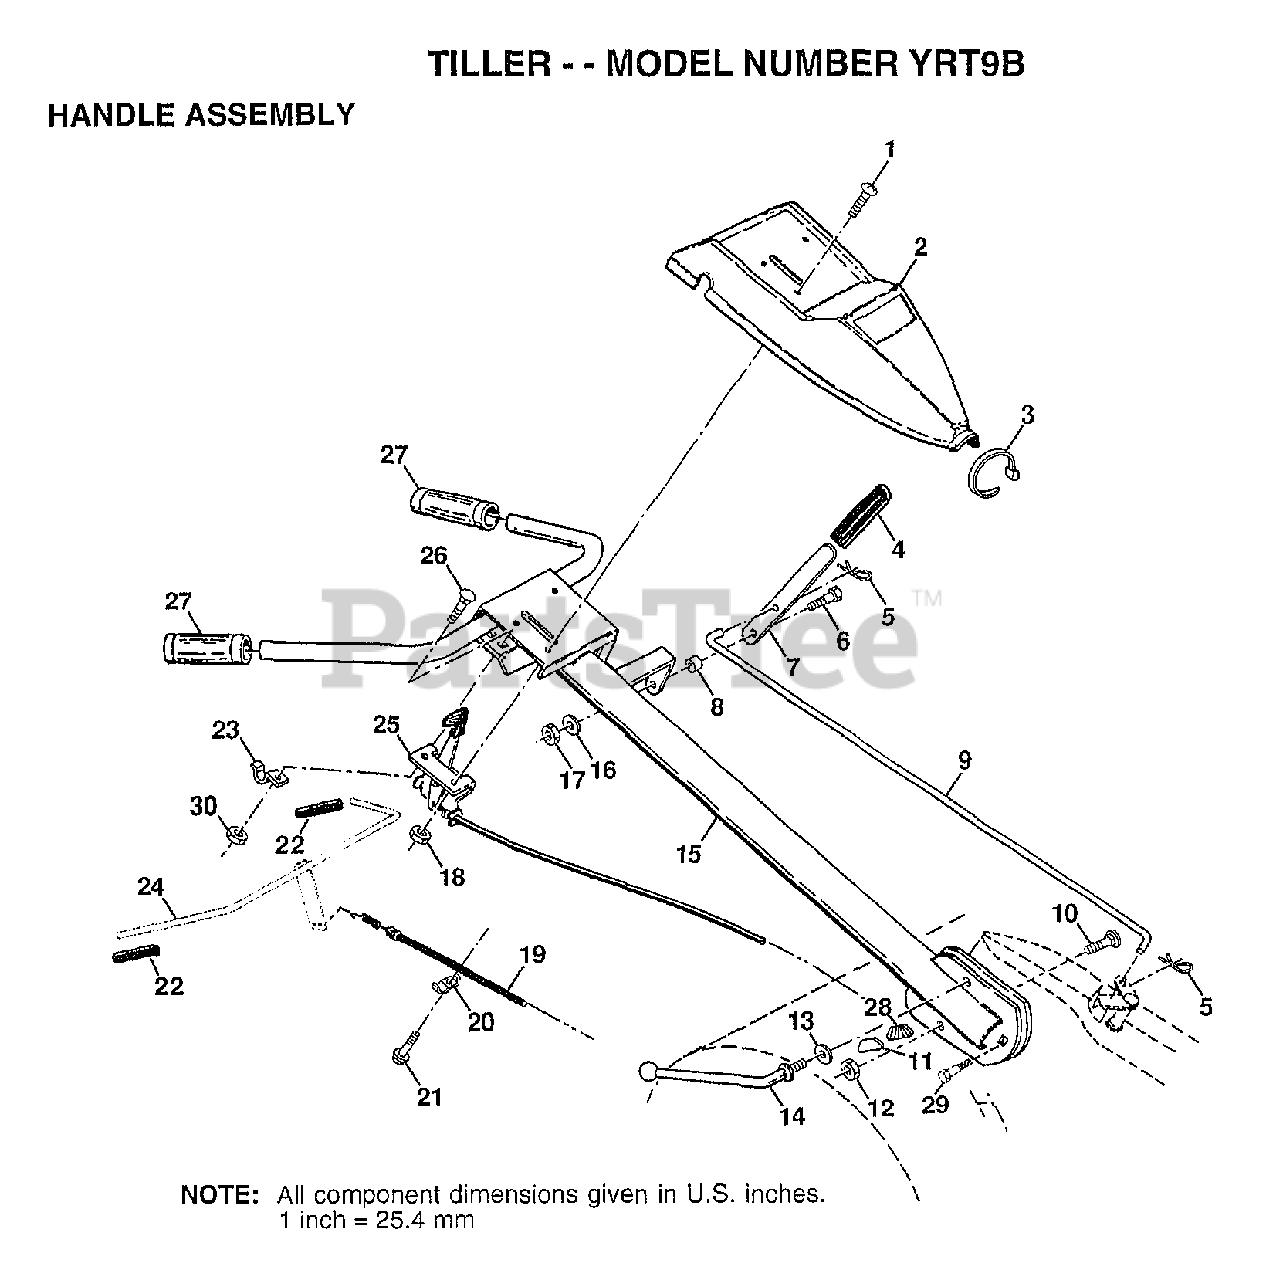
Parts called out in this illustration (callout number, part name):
1	SCREW.PNHD.10-24
2	"PANEL,CONT TI"
3	TIE CABLE CRT
4	GRIP T
5	RETAINER M
6	SHOULDER BOLT ST
7	SHIFT HANDLE CRT
8	GROMMET CRT
9	ROD.SHIFT
10	BOLT D
11	LOCK CRT
12	LOCKNUT
13	WASHER CRT
14	LEVER LOCK CRT
16	LOCKWASHER
19	CABLE.CLUTCH
20	CONDIUT CLIP T
22	GRIP BAR CRT
24	BAR ASM CONTROL
25	CONTROL.THROTTLE
26	BOLT
28	LOCK.HANDLE
29	BOLT PIVOT
30	NUT
